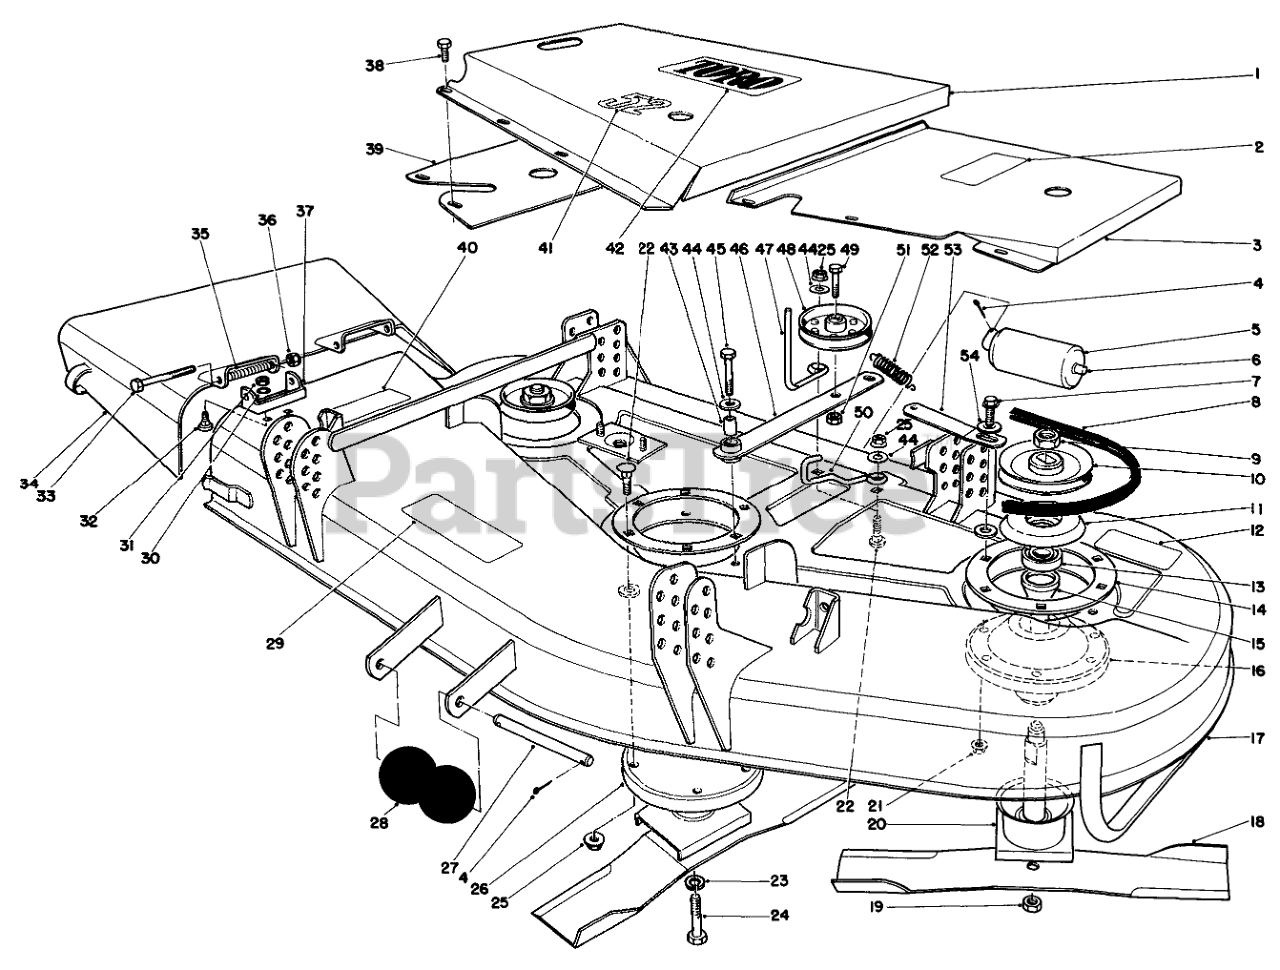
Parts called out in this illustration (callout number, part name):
1	CENTER COVER WA 52 R
2	DECAL
3	Cover
4	PIN-COTTER
5	ROLLER-DECK
6	SHAFT-ROLLER, REAR
7	SCREW-HHF
8	V-BELT
9	Locknut
10	PULLEY and HUB ASM
11	COVER-DUST
12	DECAL-CAUTION, BLADE
13	BEARING
14	SUPPORT-DECK, RING
15	SPACER-GREASE SHIELD
16	Spindle ASM
17	Deck Assembly
18	Blade
19	Locknut
20	SHAFT and SADDLE ASM
21	NUT-LOCK, FLANGE
22	SCREW-CARR
23	WASHER-LOCK/SP
24	SCREW-BLADE
25	NUT-HF
26	SPINDLE ASM
27	SHAFT-ROLLER
28	ROLLER
29	Decal-Caution
30	WASHER-LOCK
31	NUT-HEX
32	SCREW-CARR
33	SCREW-HH
34	Deflector
35	SPRING
36	NUT-HEX
37	Bracket-Pivot
38	SCREW-HHFTF
39	Cover
40	DECAL-CAUTION, DEFLECTOR
41	DECAL
42	Decal-Toro
43	SLEEVE
44	WASHER-FLAT
45	SCREW-HH
46	ARM-IDLER, DECK
47	ROD-BELT
48	Pulley
49	SCREW-HH
50	BELT GUIDE
51	NUT-HEX
52	SPRING-EXTENSION
53	Plate-Spring Support
54	WASHER-FLAT
